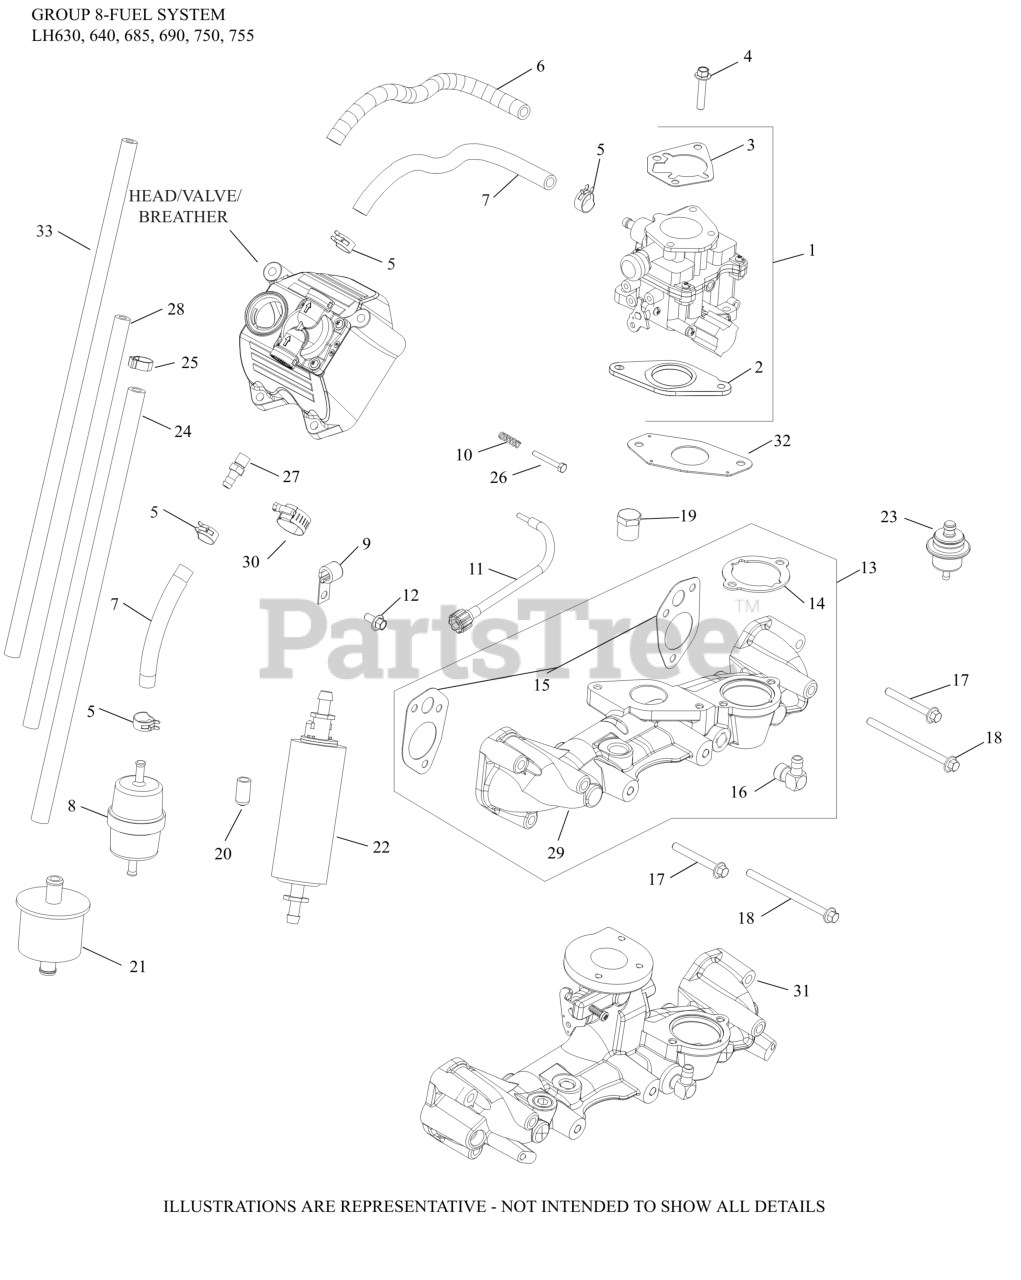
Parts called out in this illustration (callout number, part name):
1	KIT,CARB(KEIHIN) W/GASKETS
2	GASKET, CARBURETOR
5	CLAMP, HOSE (KM)-USE 25 237 31-S
5	SPRING CLAMP, HOSE
6	SLEEVE, INSULATING 14"
7	HOSE,LW PERM.FUEL 24.00"-USE 25 111 81-S
8	FILTER, FUEL
9	CLIP, CABLE
11	CABLE, CARBURETOR ADJUSTER
13	KIT, EFI INTAKE MANIFOLD
14	GASKET, THERMOSTAT
15	GASKET, INTAKE MANIFOLD
16	CONNECTOR
16	CONNECTOR, HOSE
17	SCREW, FLG M6X1.0X50
18	SCREW, FLG M6X1.0X90
NI	KIT, HIGH ALTITUDE (4,000 - 8,000 FT)
NI	KIT, HIGH ALTITUDE (ABOVE 8,000)
NI	KIT, SOLENOID
NI	KIT, REPAIR FLOAT
NI	KIT, REPAIR CARBURETOR
NI	KIT, REPAIR CHOKE
